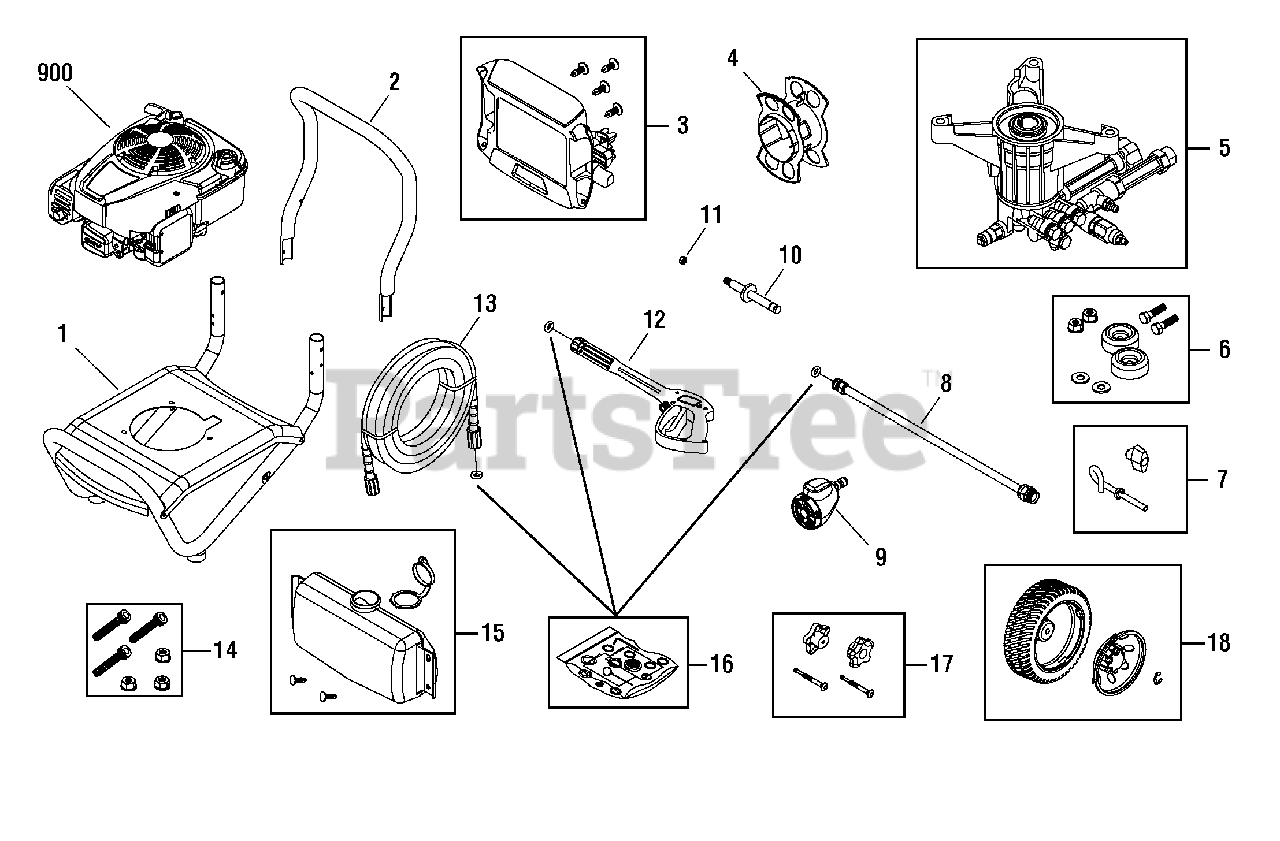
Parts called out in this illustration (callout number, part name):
6	MOUNT, Vibration
8	EXTENSION, QC
12	GUN
14	KIT, Hardware, Pump Mounting
17	KIT, Hardware, Handle
18	KIT, Wheel
900	* ENGINE
